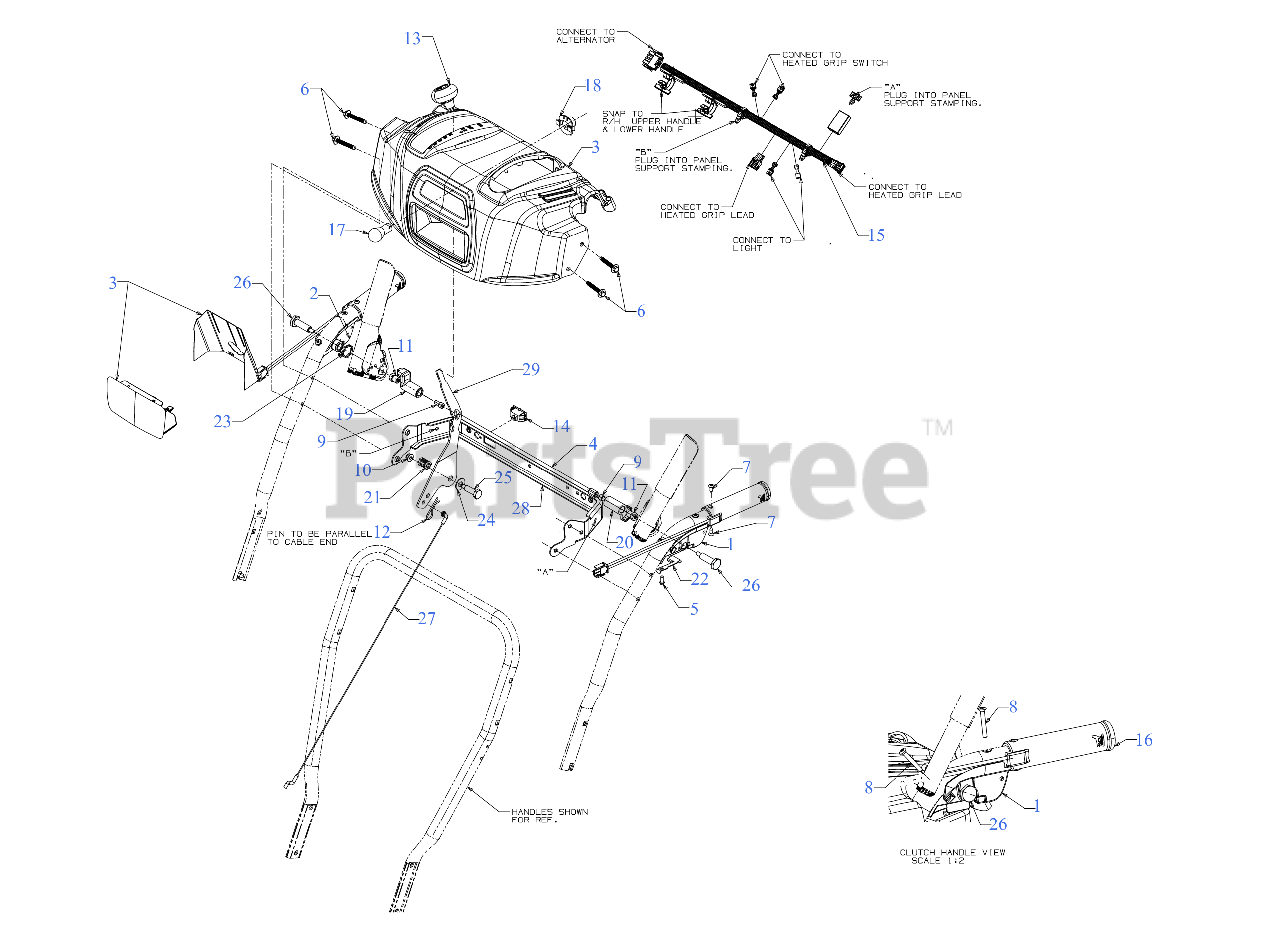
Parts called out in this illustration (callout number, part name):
1	CLUTCH LOCK HANDLE ASSEMBLY (LH)
2	CLUTCH LOCK HANDLE ASSEMBLY (RH)
3	HANDLE PANEL ASSEMBLY
4	PIVOT ROD
5	SCREW #8-16 x .50
6	SCREW 1/4-20 x 1.625
7	SCREW #10-16 x .625
8	SCREW #10-24 x 1.375
9	SCREW 1/4-20 x .50
10	FLANGE LOCK NUT
11	HEX NUT W/PATCH
12	INTERNAL COTTER PIN
13	SHIFT KNOB
14	HEATED GRIP SWITCH
15	HEATED GRIPS HARNESS
16	HARNESS-SNOW HEATED GRIP RED
17	LAMP-12 VOLT
18	HEADLIGHT SOCKET
19	LOCK PLATE
20	CLUTCH LOCK CAM
21	COMPRESSION SPRING
22	CLUTCH SPRING
23	TORSION SPRING
24	FLAT WASHER .40X.88X.060
25	SHOULDER SCREW
26	SHOULDER SCREW .437 x 1.345 1/4-20
27	SPEED SELECTOR CABLE (PLASTIC)
28	HANDLE SUPPORT BRACKET (POWDER BLACK)
29	SHIFT LEVER
